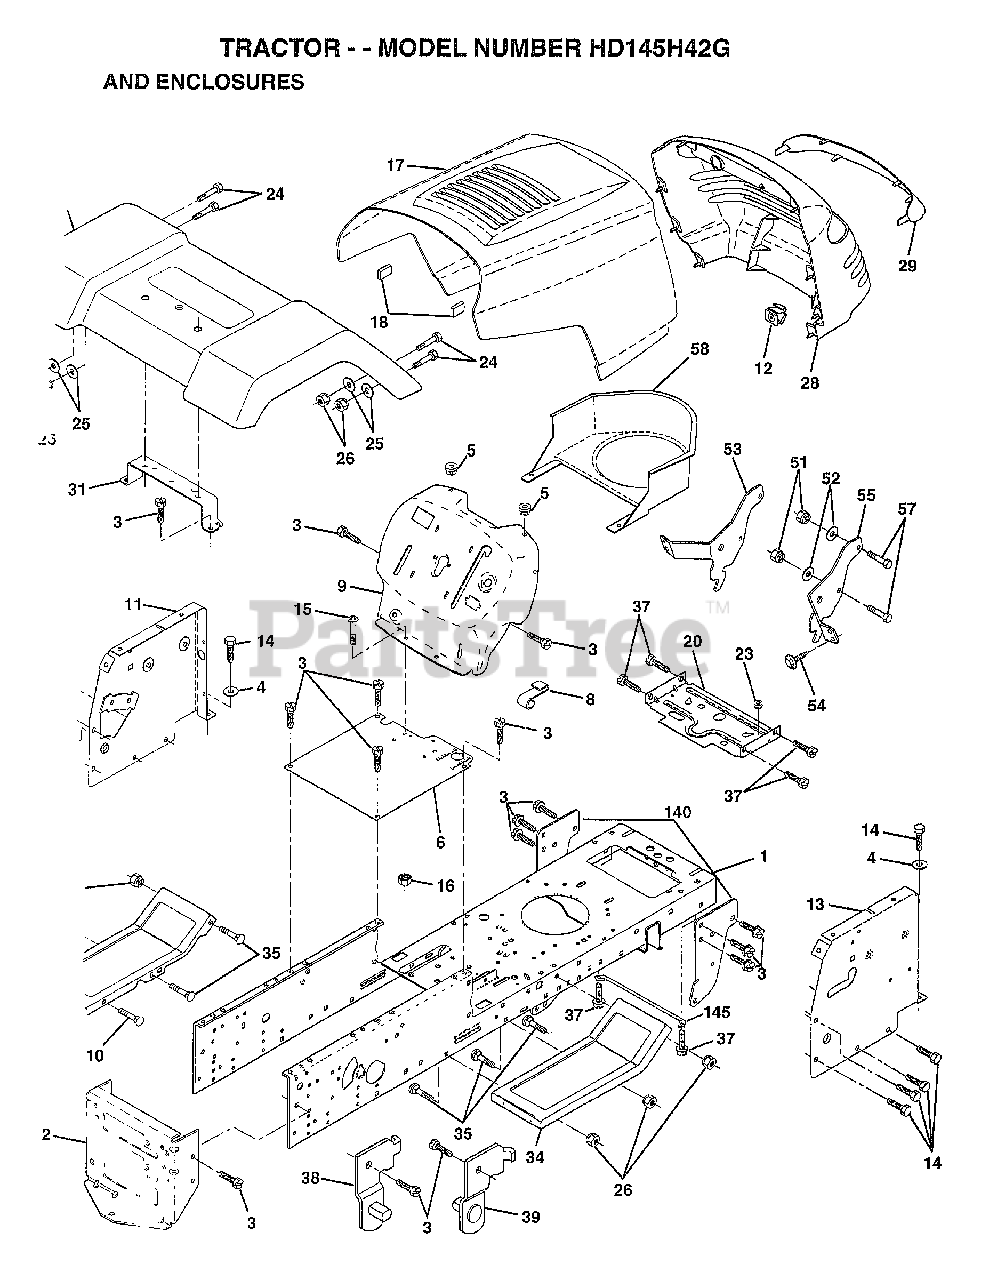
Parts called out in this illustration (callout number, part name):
1	CHASSIS ASM
3	SCREW
4	WASHER
5	BUMPER-HOOD/DASH
6	SADDLE
8	CLIP.RETAINER
9	DASH.SILKSCREENED
11	"PANEL-DASH,LH"
12	CLIP.TINNERMAN
14	SCREW LT
15	SCREW
17	"HOOD W/TRIM,MS428"
20	"PLATE-MTG,BATT/FU"
24	BOLT
25	WASHER
26	NUT
28	GRILLE-MS428
29	LENS GRILLE
30	FENDER ASM LT W/S
31	BRKT FENDER
33	FOOTREST LH
34	FOOTREST RH
35	BOLT
37	SCREW LT
38	BRACKET ASM LH
39	BRACKET ASM RH
51	NUT
52	WASHER
53	BRACKET.GRILLE.LH
55	BRACKET.GRILLE.RH
58	AIR DUCT
140	BRKT SUSPENSION
145	"ROD POVOT,CHASSIS"
